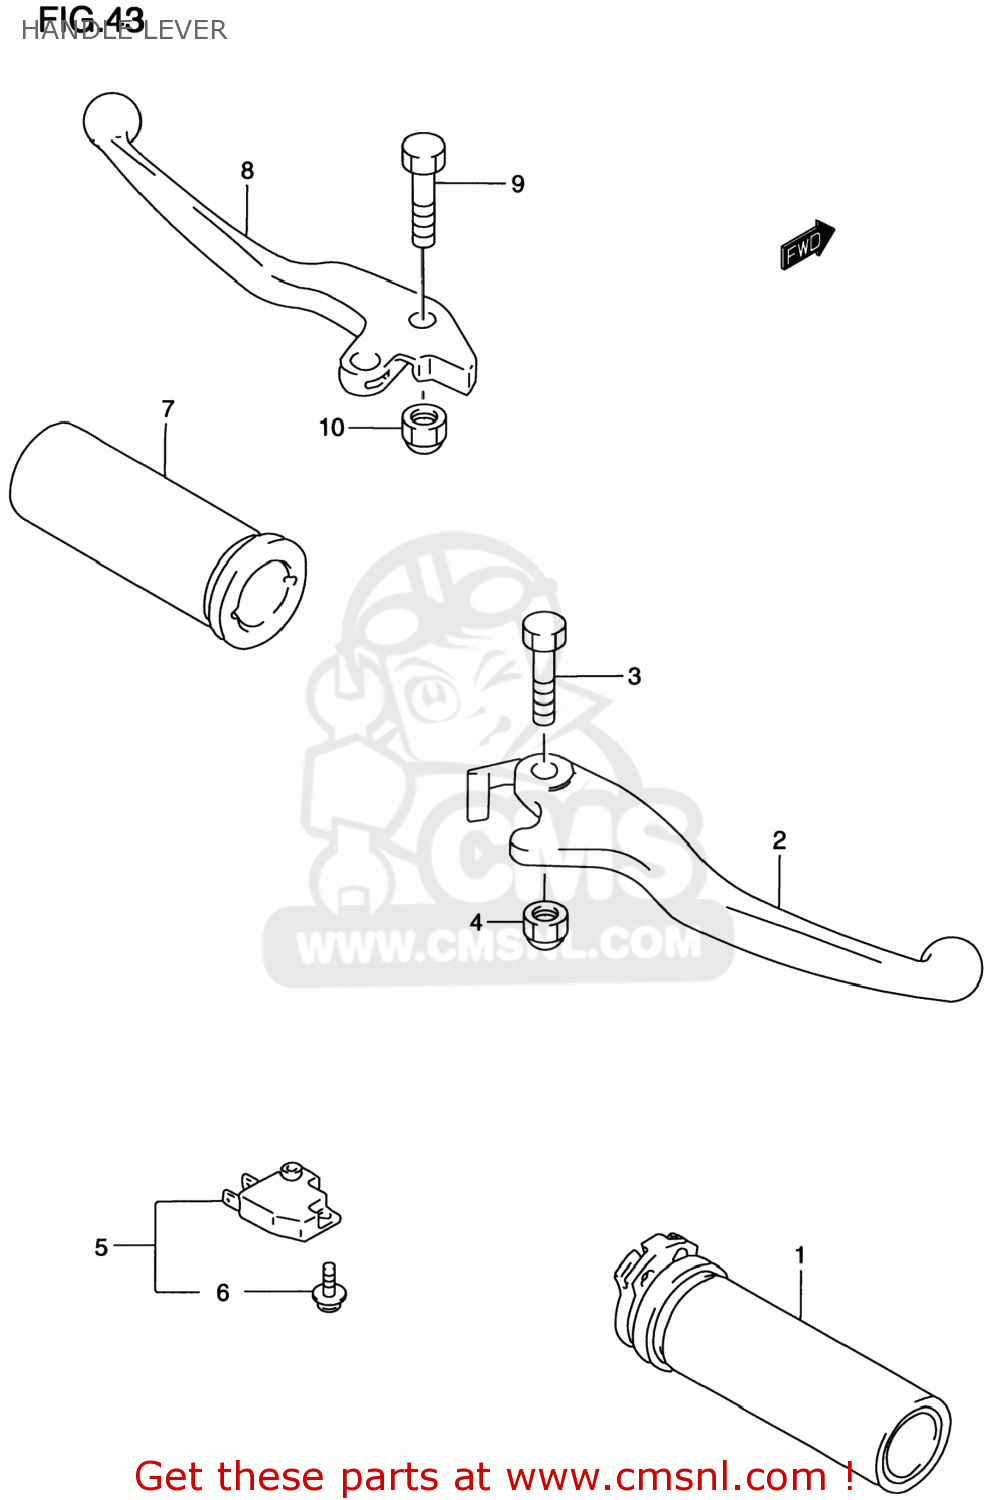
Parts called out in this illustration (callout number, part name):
1	GRIP,THROTTLE
2	LEVER,BRAKE
3	BOLT,LEVER SET
4	NUT 6MM
5	SWITCH ASSEMBLY,STOP
6	SCREW
7	GRIP,L
8	LEVER,CLUTCH (SILVER)
9	BOLT,LEVER SET
10	NUT 6MM
